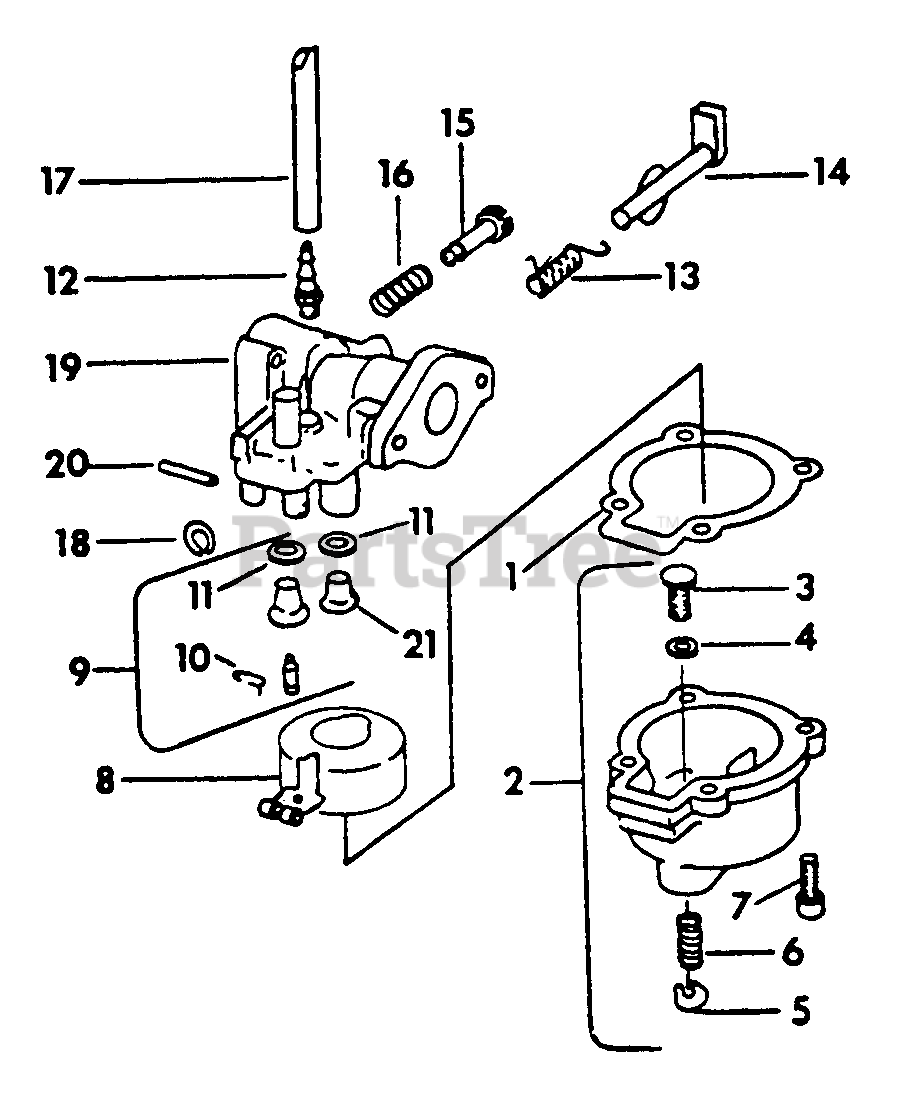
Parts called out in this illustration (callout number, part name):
1	GASKET, FLOAT CHAMBER
2	FLOAT CHAMBER & DUMP VALVE ASSY
3	STEM, VALVE
4	SEAT, VALVE
5	KEEPER, VALVE
6	SPRING, VALVE
7	SCREW, 8-32 X 1/2 ZND FIL-HD SLT MACH
9	FLOAT VALVE & SEAT
11	WASHER, FLOAT VALVE SEAT
12	CONNECTOR, TUBING
13	SPRING, THROTTLE
14	SHAFT W/DISC, THROTTLE
15	SCREW, AIR ADJ
16	SPRING, NEEDLE ADJ
17	TUBING, PRIMER
19	BODY ASSY, CARBURETOR
20	PIN, FLOAT ARM HINGE
21	PLUG, NOZZLE
